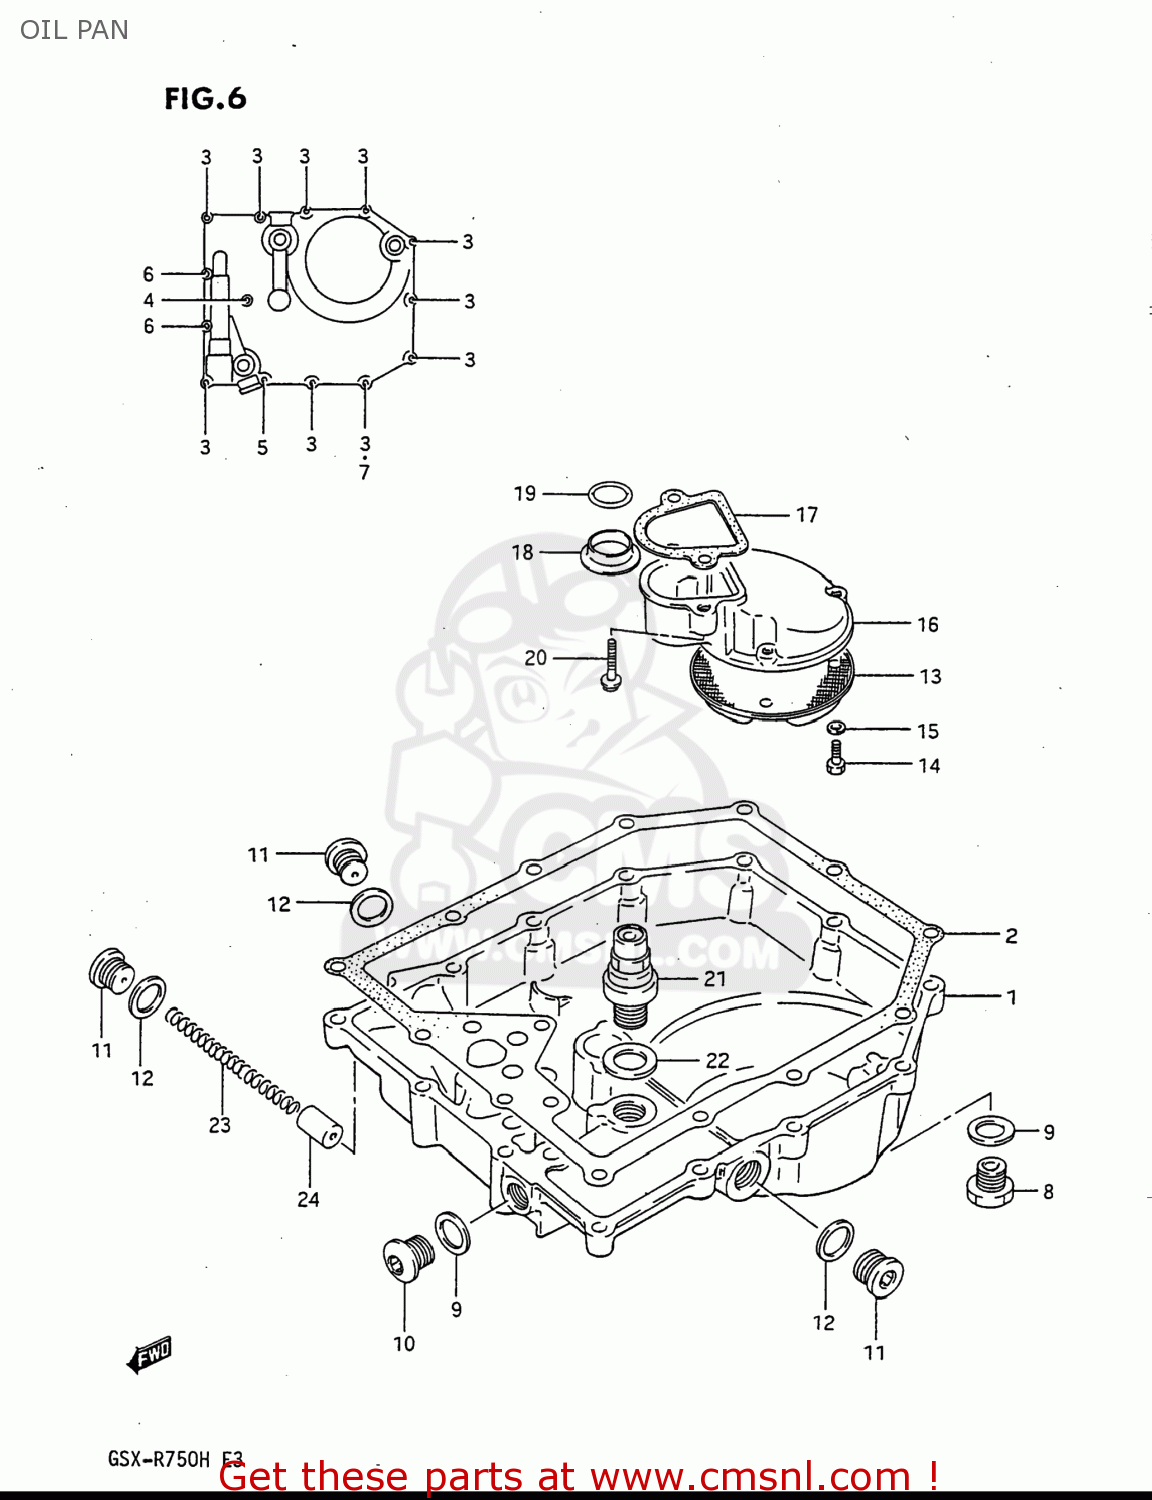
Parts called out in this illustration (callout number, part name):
1	PAN,OIL
2	GASKET,OIL PAN (NAS)
3	BOLT
4	BOLT
5	BOLT
6	BOLT
7	GASKET(5.8X11X1.2) (NAS)
8	PLUG
9	GASKET(14X19.2X2) (NAS)
10	PLUG
11	PLUG
12	GASKET(16X22X2) (NAS)
13	STRAINER,ENGINE OIL
14	BOLT
15	WASHER,LOCK
16	PROTECTOR,OIL STRAINER
17	GASKET,OIL STRAINER PROTECTOR (NAS)
18	GASKET,OIL OUTLET (NAS)
19	O RING(D:3.2,ID:17.8)
20	BOLT
21	VALVE ASSEMBLY,OIL RELIEF
22	GASKET(16X22X2) (NAS)
23	SPRING
24	PLUNGER,OIL CONTROLL
